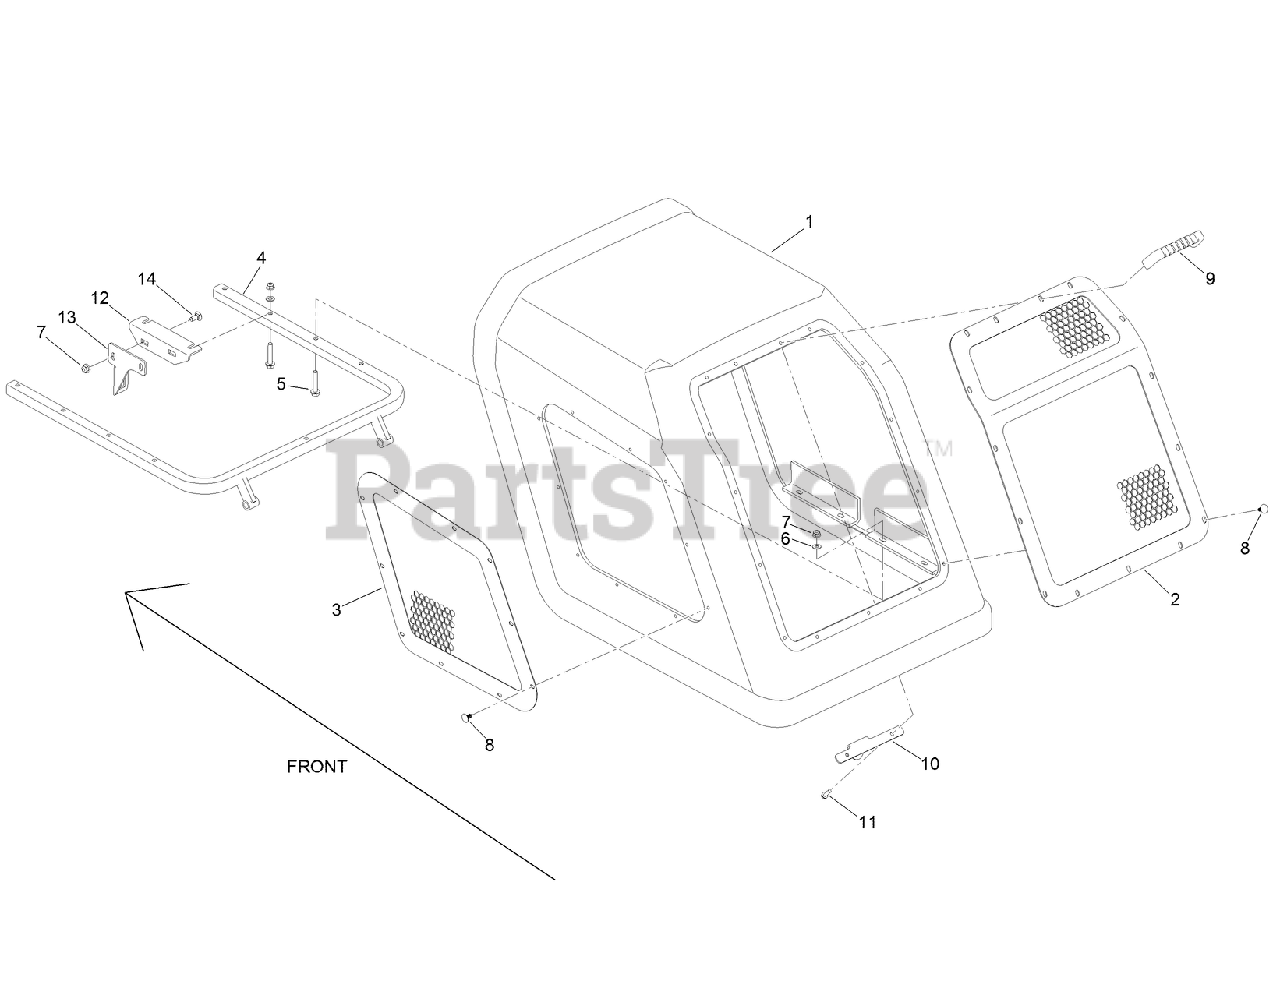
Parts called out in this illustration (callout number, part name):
1	HOOD-REAR
2	SCREEN-REAR
3	SCREEN-SIDE
4	FRAME-HOOD, REAR
5	SCREW-HWH
6	WASHER-FLAT
7	NUT-HF, NI
8	PLUG-PLASTIC
9	HANDLE-DOOR
10	PLATE-HANDLE, REAR HOOD
11	SCREW-HWH
12	BRACKET-MOUNT, REAR CATCH
13	BRACKET-CATCH, REAR
14	BOLT-CARR
